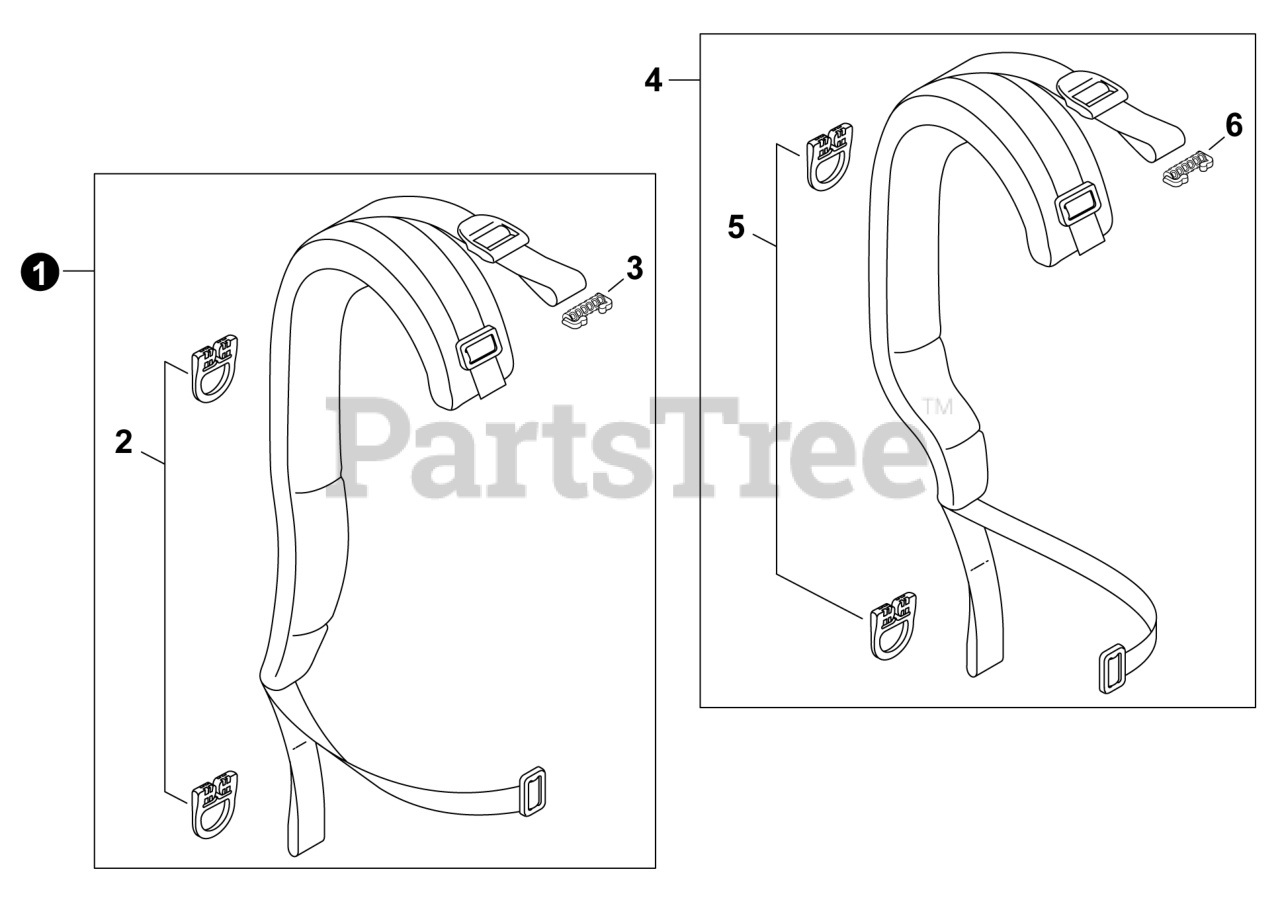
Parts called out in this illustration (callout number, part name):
1	HARNESS ASSY, LEFT (PB-8010)
2	BUCKLE, HARNESS
4	HARNESS ASSY, RIGHT (PB-8010)
5	BUCKLE, HARNESS
